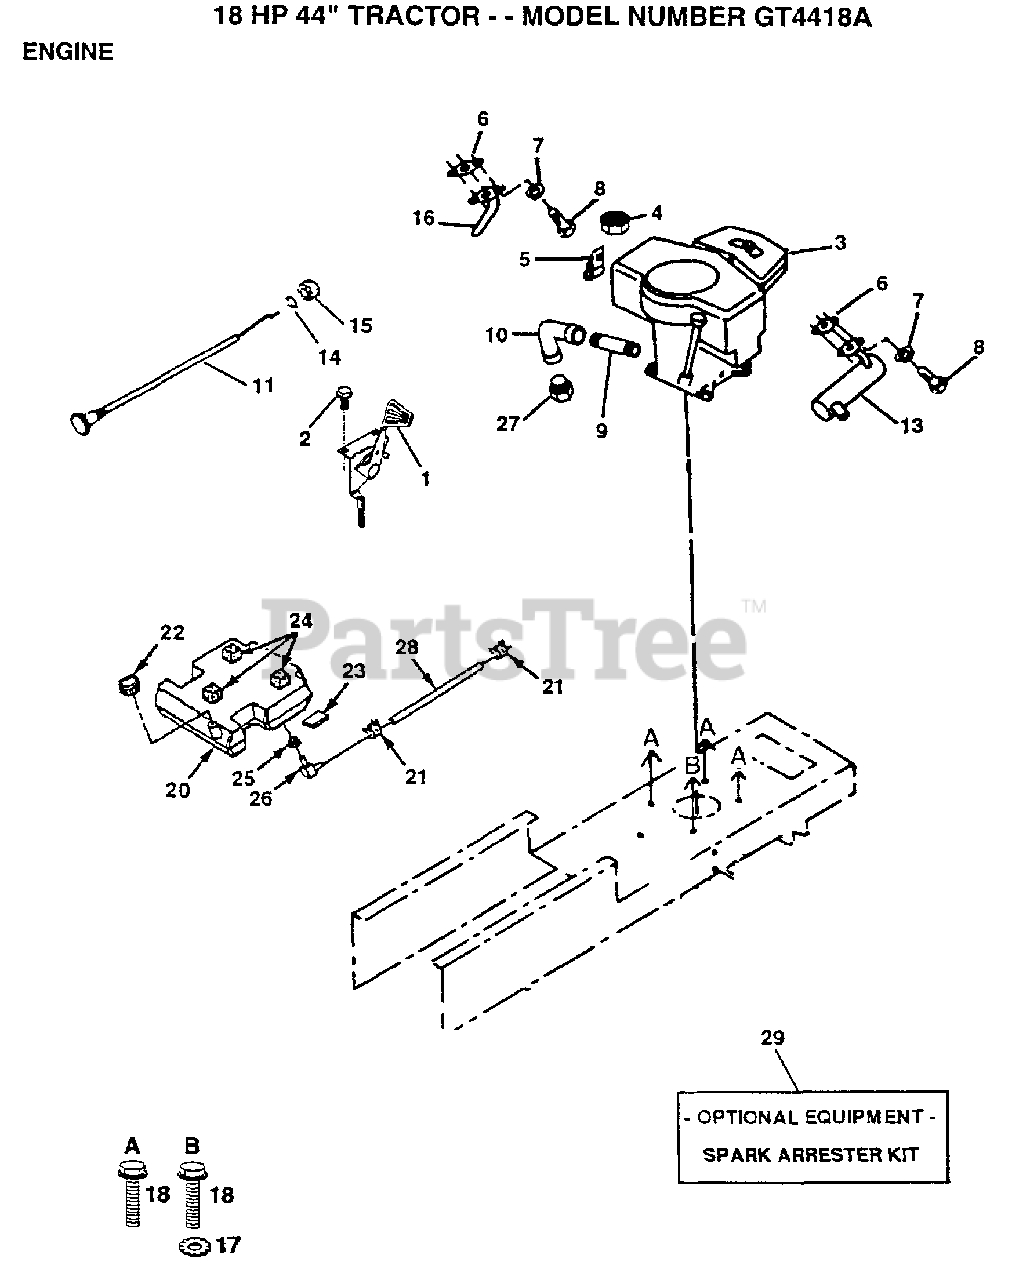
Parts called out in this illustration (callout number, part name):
1	CONTROL.THROTTL
2	SCREW LT
3	ENGINE B&S 18HP
4	NUT
5	CLIP T
7	LOCKWASHER
9	PIPE NIPPLE LT
10	ELBOW
11	CHOKE CONTROL
14	LOCKWASHER
16	EXHAUST TUBE T
17	LOCKWASHER
18	SCREW LT
20	TANK FUEL 1.9 NAT
21	HOSE CLAMP
22	CAP ASM FUEL
23	PAD IDLER TI
24	PAD-SPACER LT
25	BUSHING OUTLET T
26	STEM.TANK.FUEL
28	FUEL LINE T
